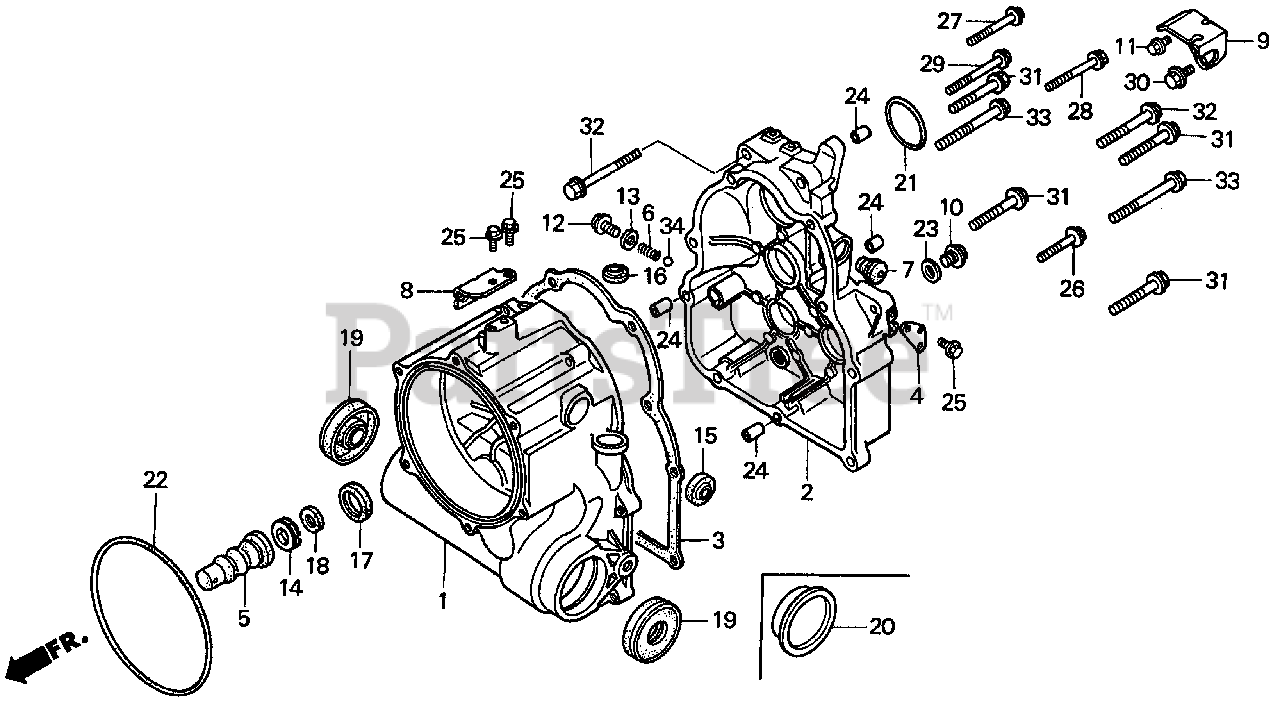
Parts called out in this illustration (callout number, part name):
1	CASE, TRANSMISSION
2	COVER, TRANSMISSION CASE
3	GASKET, TRANSMISSION CASE
4	BRACKET, CLUTCH SPRING
5	BOOT, SHIFT FORK SHAFT
6	SPRING, BALL SETTING
7	CAP, TRANSMISSION OIL
8	BRACKET, MAIN CLUTCH CABLE
9	BRACKET, AUGER CLUTCH CABLE
10	BOLT, SEALING (12X10)
11	BOLT, FLANGE (6X14)
12	BOLT, CHECK (8MM)
13	WASHER (8MM)
14	GROMMET, BOOT COVER
15	OIL SEAL (14X28X7) (ARAI)
16	OIL SEAL (14X20X4) (NIPPON OIL-SEAL)
17	OIL SEAL (22X32X5)
18	OIL SEAL (12X22X6)
19	OIL SEAL (20X47X9.7)
21	O-RING (47.7X2.5) (ARAI)
21	O-RING (47.7X2.5) (NOK)
22	O-RING (144.4X3.1)
23	WASHER, DRAIN PLUG (12MM)
24	PIN A, DOWEL (8X14)
25	BOLT, FLANGE (6X12)
26	BOLT, FLANGE (6X35)
27	BOLT, FLANGE (6X40)
28	BOLT, FLANGE (6X45)
29	BOLT, FLANGE (6X55)
30	BOLT, FLANGE (8X20)
31	BOLT, FLANGE (8X40)
32	BOLT, FLANGE (8X55)
33	BOLT, FLANGE (8X65)
34	BALL, STEEL (#8) (1/4)
